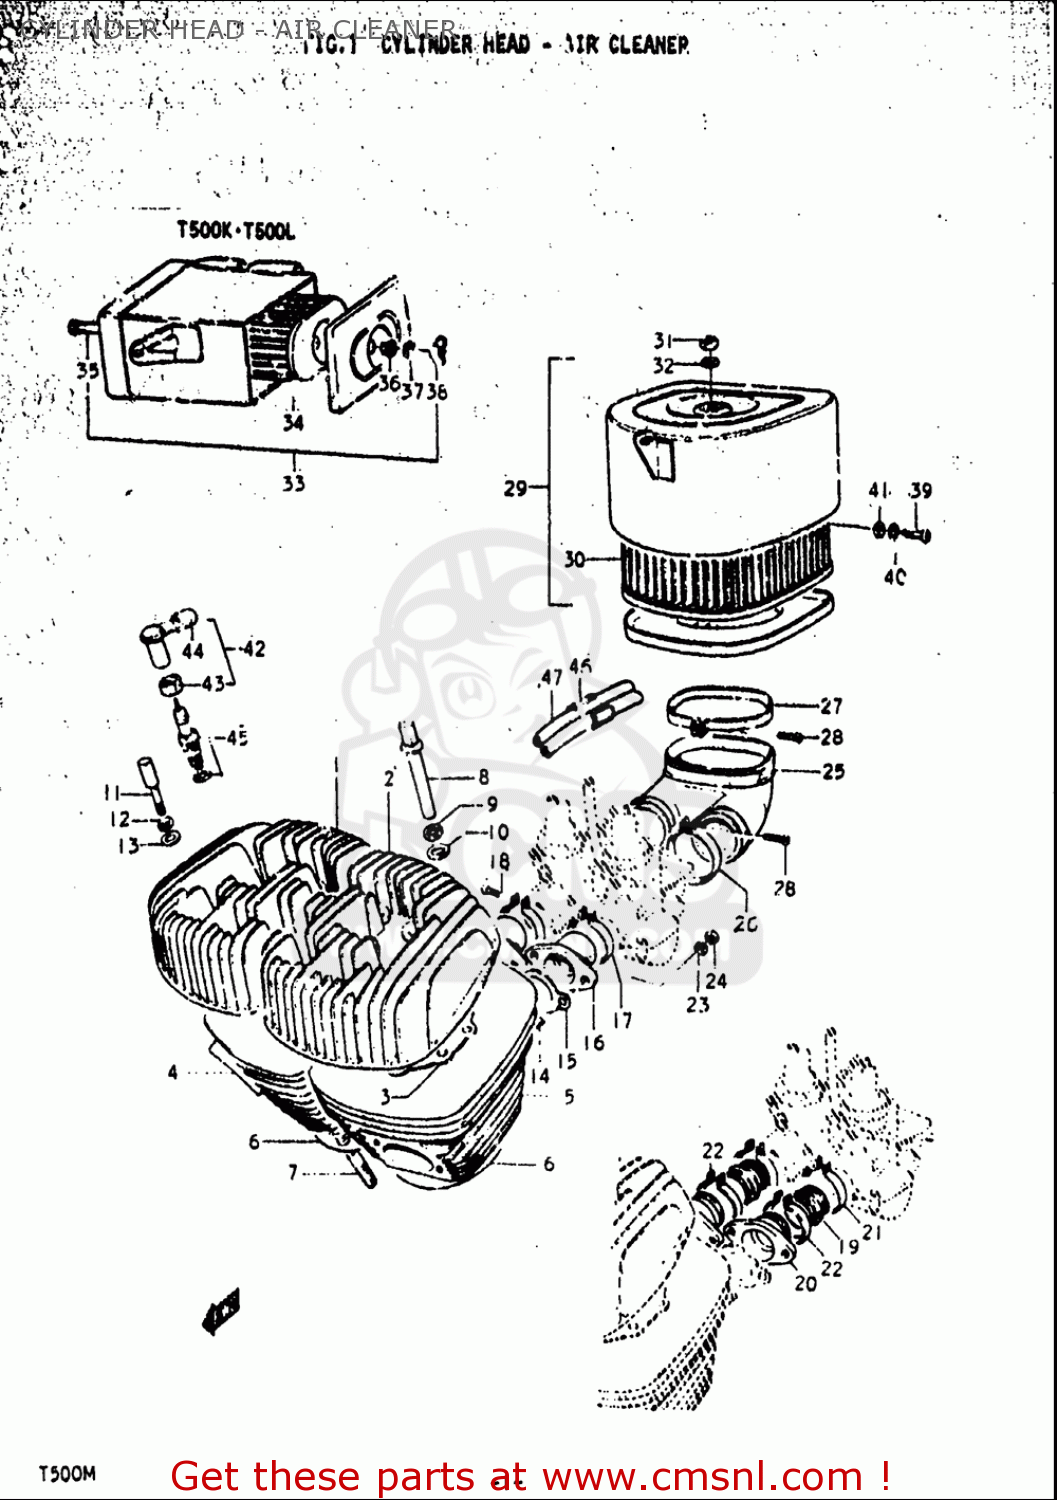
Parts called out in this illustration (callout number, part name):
1	HEAD,CYLINDER
2	CYLINDER HEAD, LH
3	GASKET,CYLINDER HEAD (NAS)
4	CYLINDER
5	CYLINDER
6	GASKET,CYLINDER (MCA)
7	STUD BOLT
8	NUT (10MM)
9	LOCK WASHER
10	WASHER
11	BOLT
12	LOCK WASHER
13	WASHER
14	STUD BOLT
15	GASKET,CARBURETOR (NAS)
16	PIPE,INTAKE
17	CLAMP
18	SCREW
19	PIPE,INTAKE
20	PIPE,INTAKE NO.2
21	CLAMP
22	CLAMP
23	LOCK WASHER
24	NUT
25	TUBE,AIR CLEANER OUTLET
26	1
